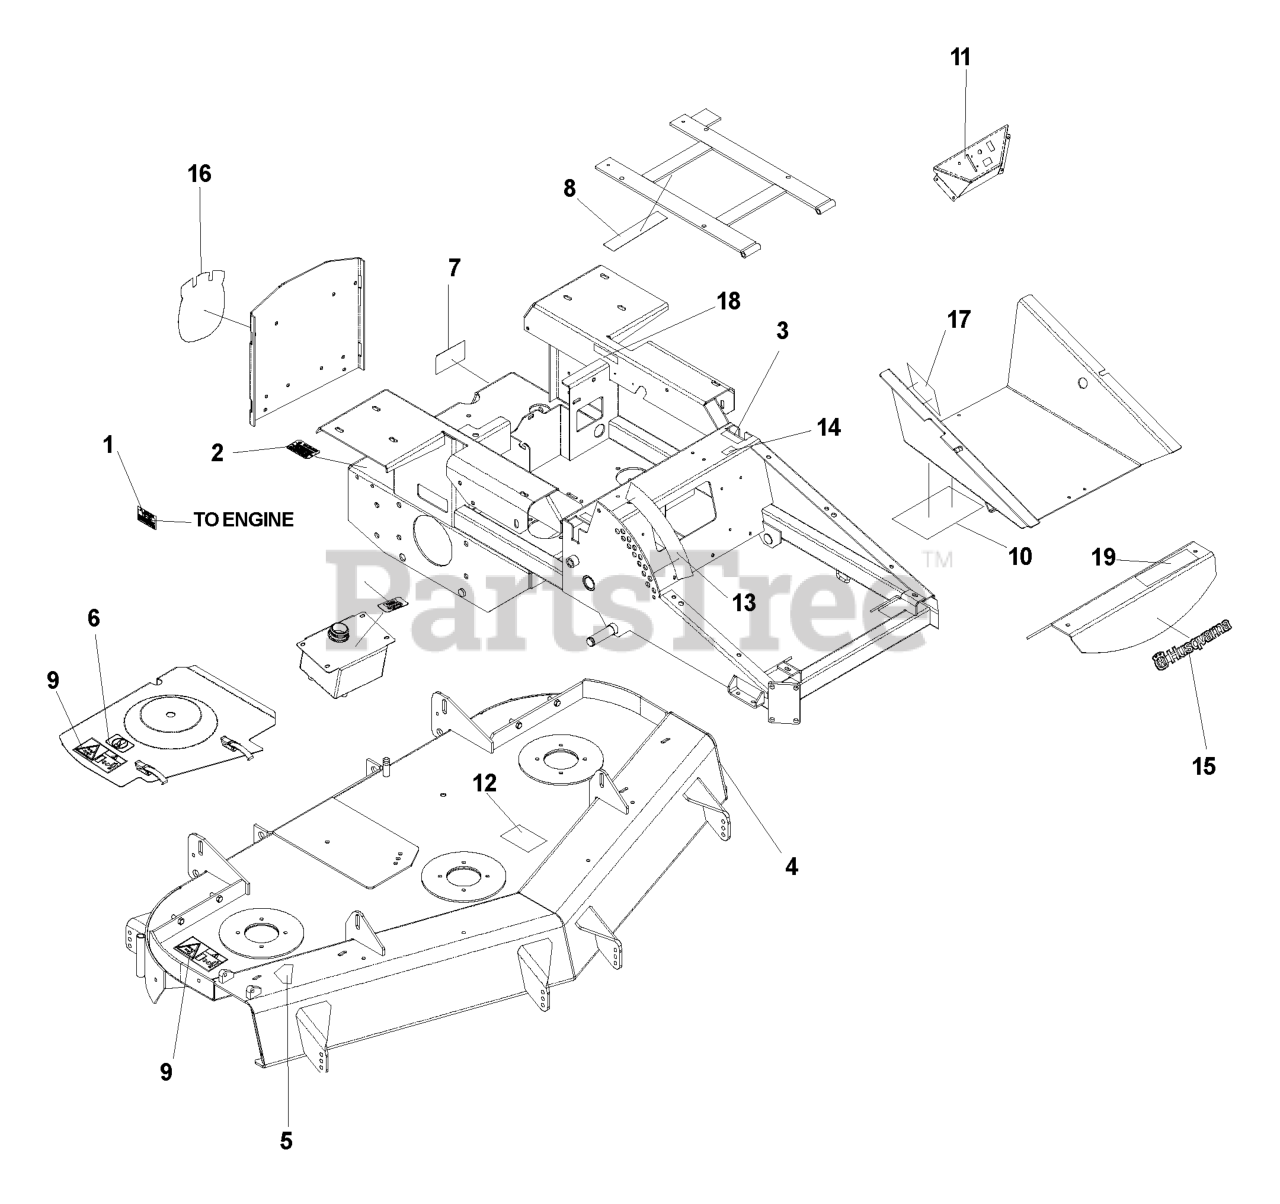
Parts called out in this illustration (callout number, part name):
1	DECAL, EXHAUST
2	DECAL, PROP. 65
3	DECAL, MOTION CONTROL
4	DECAL, NASCAR
5	DECAL, CPSC
6	DECAL, NO STEP
7	DECAL, BELT DRIVE
8	EURO DECAL-BATTERY WARNIN6
9	DECAL, EURO SEVERING
10	SERVICE DECAL
11	DECAL, CONSOLE
12	DECAL, BELT ROUTING
13	DECAL, HEIGHT ADJ
14	DECAL, F.S.T.
15	DECAL, HUSQ 12" BLUE
16	DECAL, CROWN H 5-1/4 SILVER
17	DECAL, WARNING
18	DECAL, RELAYS
19	DECAL, IZ4217
19	DECAL, IZ4817
19	DECAL, IZ4821
19	DECAL, IZ5223
19	DECAL, IZ5225
19	DECAL, IZ6125
